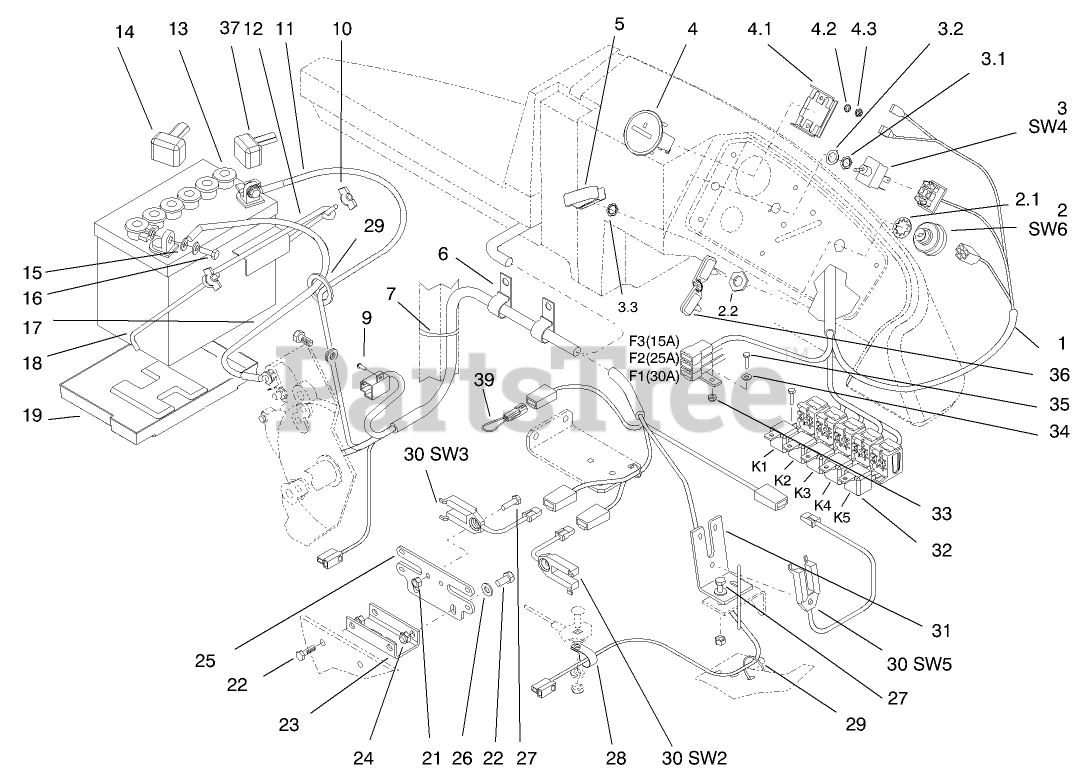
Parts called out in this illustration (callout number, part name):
1	HARNESS
2	IGNITION SWITCH ASM
2.2	WASHER-LOCK
3	SWITCH-TOGGLE, SEALED
3.1	NUT-HEX, SPECIAL
3.2	TAB-WASHER
4	Hourmeter
4.1	CLAMP-HOUR METER
4.2	WASHER-LOCK
4.3	NUT-HEX
5	COVER-PTO SWITCH
6	CLAMP-J
7	TIE-CABLE
9	SCREW-TAP
10	NUT-WING
11	WIRE ASM (NEGATIVE)
12	HOLDDOWN-BATTERY
13	Battery
14	BOOT-TERMINAL
15	WASHER-FLAT
16	SCREW-HH
17	WIRE ASM
18	RETAINER-BATTERY
19	TRAY-BATTERY
21	NUT-LOCK, NI
22	SCREW-HH
23	CHANNEL-MOUNT, SWITCH
24	NUT-LOCK, NI
25	PLATE-MOUNT, SWITCH
26	WASHER-PLAIN
27	SCREW-HH
28	CLAMP-R
29	TIE-CABLE
30	SWITCH-INTERRUPTER
31	ANGLE - MOUNT,SWITCH
32	RELAY
33	NUT-LOCK, NI
34	WASHER-FLAT
35	SCREW-HWH
36	KEY-IGNITION
39	JUMPER
